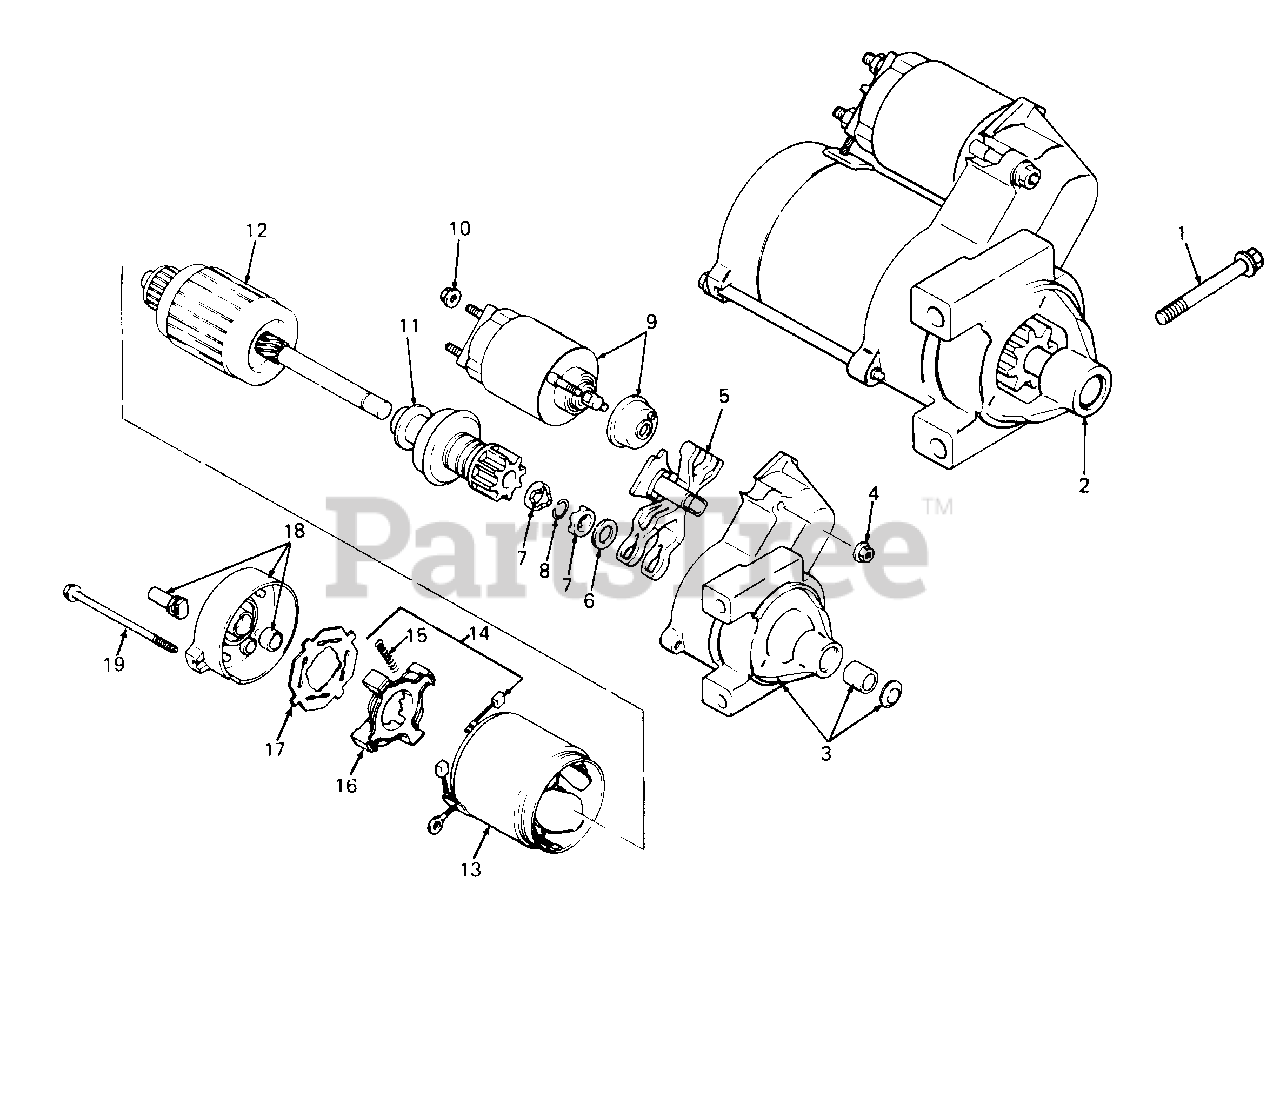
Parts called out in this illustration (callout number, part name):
1	Screw, M8 x 1.25 x 80.6
2	Starter Assy, Solenoid Shift
3	Cap, Drive End
4	Nut, Starter
5	Lever, Starter Drive
6	Washer, Thrust
7	Nut, Stop Collar
8	Ring, Retainer
11	Drive, Pinion
14	Kit, Brush
15	Spring, Brush
16	Holder, Brush
18	Cap, Commutator End
